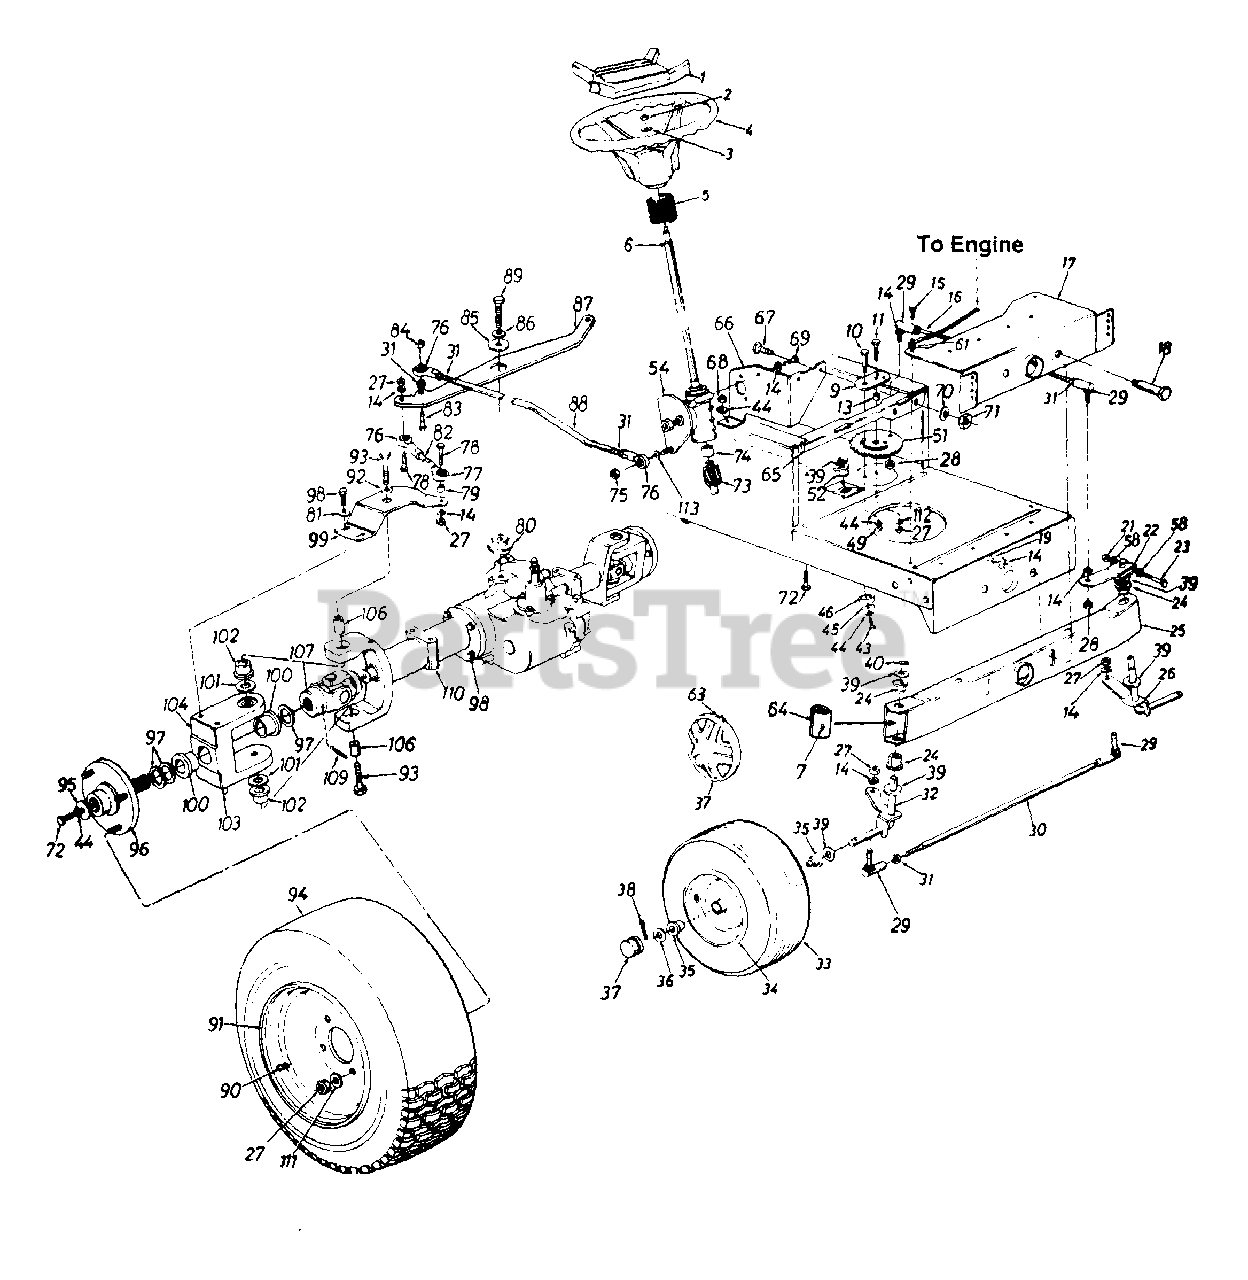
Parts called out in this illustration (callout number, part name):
1	Steering Wheel Insert
2	Hex L-Nut 5/16-24 Thd.
3	Belleville Wash. .345" I.D.
4	Steering Wheel (4 Spoke)
5	Steering Bellow
6	Steering Shaft Ass'y.
7	Grease Fitting
9	Retainer Plate
10	Shoulder Bolt .437" Dia. x .35" Lg. 5/16-18 Thd.
11	Hex Bolt 3/8-24 x 1.0" Lg. (Grade 5)
13	Spacer .380" I.D. x .625" O.D. x .227"
14	L-Wash. 3/8" I.D.
15	Hex Wash. Hd. Self-Tap Scr.
16	Steering Drag Link
17	Front Pivot Brkt.
18	Shoulder Bolt .498" Dia. x 2.04" Lg. 3/8-16 Thd.
19	Hex Nut 3/8-16 Thd.
21	Hex Cent. L-Nut 5/16-24 Thd.
22	Steering Arm Front Axle
23	Hex Bolt 5/16-24 x 2.00" Lg. (Grade 5)
24	Hex Flg. Brg. .634" I.D.
26	Front Axle Ass'y.- L.H.
27	Hex Nut 3/8-24 Thd.
28	Hex Jam Nut 3/8-24 Thd.
29	Ball Joint 3/8-24 Thd.
30	Tie Rod
31	Hex Jam Nut 3/8-24 Thd.
32	Front Axle Ass'y.- R.H.
33	Wheel Ass'y. Comp.
34	Front Wheel Rim Only
35	Bearing
36	Fl-Wash. .635" I.D. x 1.59" O.D.
37	Front Hub Cap (Black)
38	Cotter Pin 1/8" Dia. x 1.25" Lg.
39	Fl-Wash. .640" I.D. x .24" O.D.
40	Push Cap
43	Hex L-Bolt 5/16-18 x .62"
44	L-Wash. 5/16" I.D.
45	Fl-Wash. .33" I.D. x 1.25" O.D.
46	Spacer (Plastic)
49	Hex Nut 5/16-18 Thd.
51	Steering Gear Segment
52	Hex Fig. Brg. .634 I.D.
54	Steering Ass'y. Comp.
58	Wave Wash. .32" I.D. x .62"
61	Ext. I-Wash. 5/16" I.D.
63	Spring Clip (Used w/Ref. 37)
64	Pivot Bar End Cap
65	Horizontal Cross Bracket
66	Vertical Mounting Bracket
67	Hex Bolt 1/4-28 x .75" Lg.
68	Hex Nut 5/16-24 Thd.
69	Hex Bolt 3/8-16 x 1.0" Lg.
70	Bell-Wash. .265" I.D. x .75"
71	Hex Nut 1/4-28 Thd.
72	Hex Bolt 5/16-24 x .75" Lg.
73	Pinion Shaft
74	Steering Shaft Splined Coupler
75	Hex L-Nut 3/8-24 Thd.
76	Rod End 3/8-24 Thd.- R.H.
77	Rod End 3/8-24 Thd.- L.H.
78	Hex Bolt 3/8-24 x 1.5" Lg. (Gr. 5)
79	Spacer .38" I.D. x .625"
80	Shld. Spacer .51" I.D.
81	Bell-Wash. .38" I.D. x .88"
82	Tie Rod
83	Hex Bolt 3/8-24 x 1.25" Lg.
84	Hex Patch L-Nut 3/8-24 Thd.
85	Fl-Wash. .531" I.D. x 1.75"
86	Bell-Wash. .505" I.D. x 1.0"
89	Hex Bolt 1/2-13 x 1.5" Lg. (Gr. 5)
90	Air Valve
93	Hex Bolt 1/2-20 x 1.75" Lg. (Gr. 5)
94	Rear Wheel Ass'y. Comp.
95	Fl-Wash. .33" I.D. x 1.25"
96	Wheel Flange Ass'y.
97	Fl-Wash. 1.0" x 1.56"
98	Hex Bolt 3/8-24 x 1.25" Lg.
101	Fl-Wash. .76" I.D. x 1.5"
102	Flange Brg. 3/4" I.D.
103	Grease Fitting
104	Wheel Brg. Housing
106	Pivot Sleeve
107	U-Joint
109	Grooved Roll Pin 1.0" Lg.
110	Axle Horn Ass'y.
111	Bell-Wash. .38" I.D. x .88"
112	Bell-Wash. .39" I.D. x 1.38"
113	Fl-Wash. .385" I.D. x .62"
